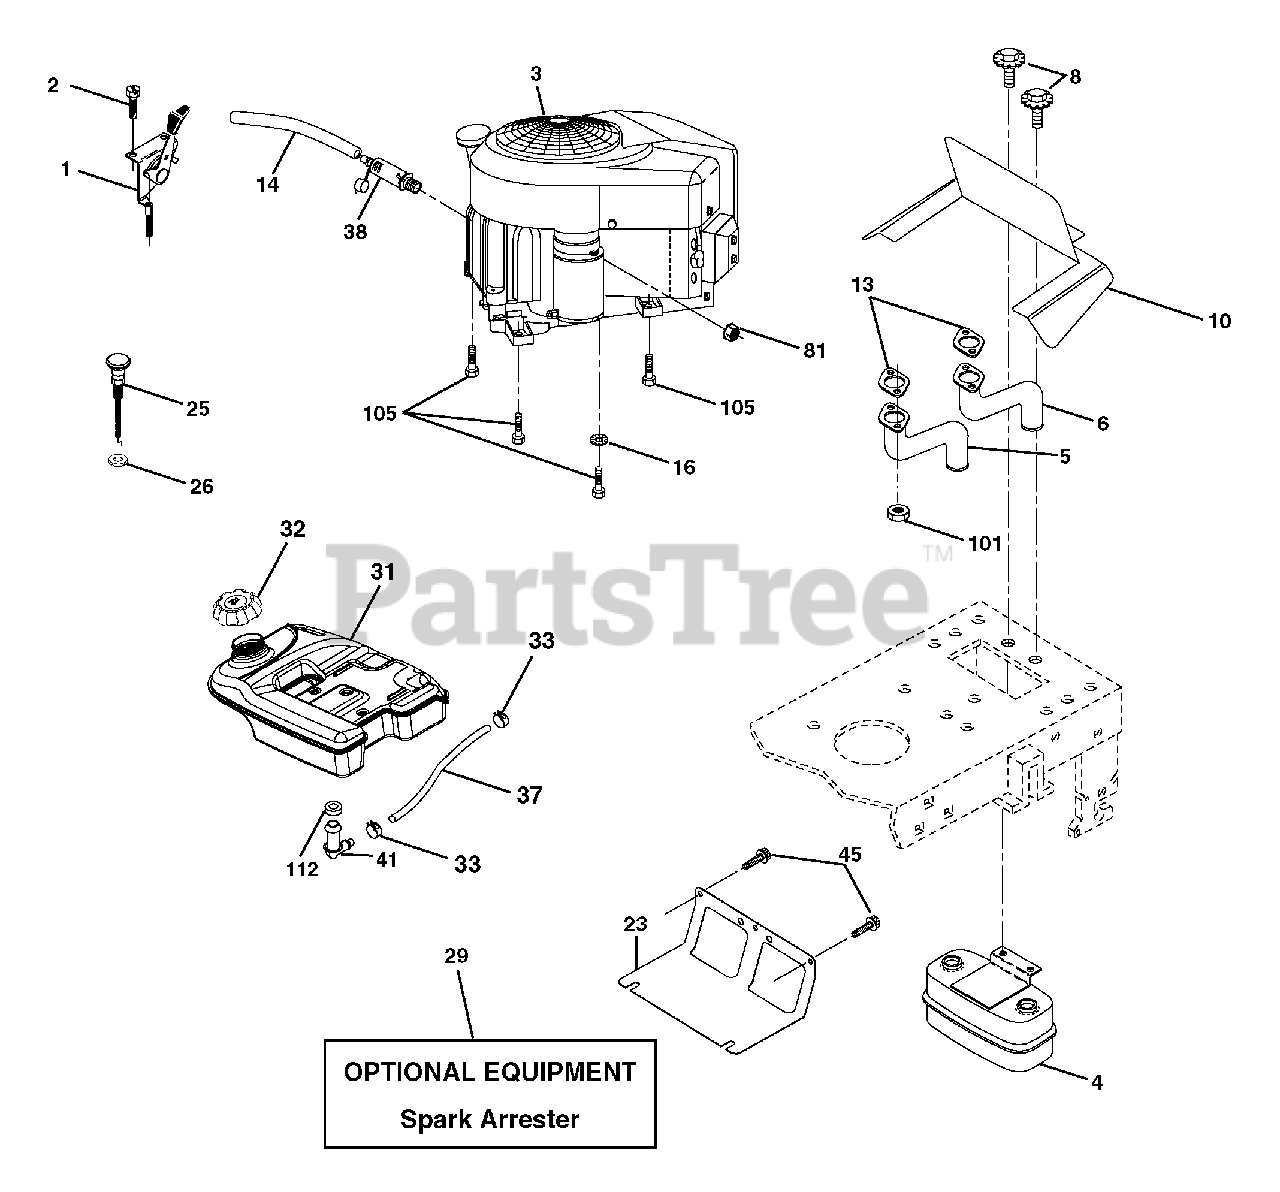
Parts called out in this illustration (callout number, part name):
1	Control Throt Flg
2	Screw Hex Thd Cut 1/4-20x5/8 T
3	Engine
4	Muffler Asm Twin Lo-Tone
5	Exhaust Tube Lh
6	Exhaust Tube Rh
8	Bolt 5/16-18unc x 3/4 W/Sems
10	Shield Browning
13	Gasket Muffler
14	Tube Drain Oil Easy
16	Washer Lock Ext Tooth 3/8
23	Shield Browning
25	Choke Control
26	Nut, Keps 3/8-24 Unf
29	Kit Spark Arrestor (Flat Scrn)
32	Cap Asm Fuel
33	Clamp Hose Blk
37	Line Fuel
38	Plug Drain Oil
41	Stem Tank Fuel
45	Screw Hexwsh Thdr 3/8-16 x 3/4
81	Nut Keps Hex 1/4-20
101	Nut Flange M8-1.25
105	Screw 3/8-16 x 1
112	Bushing
